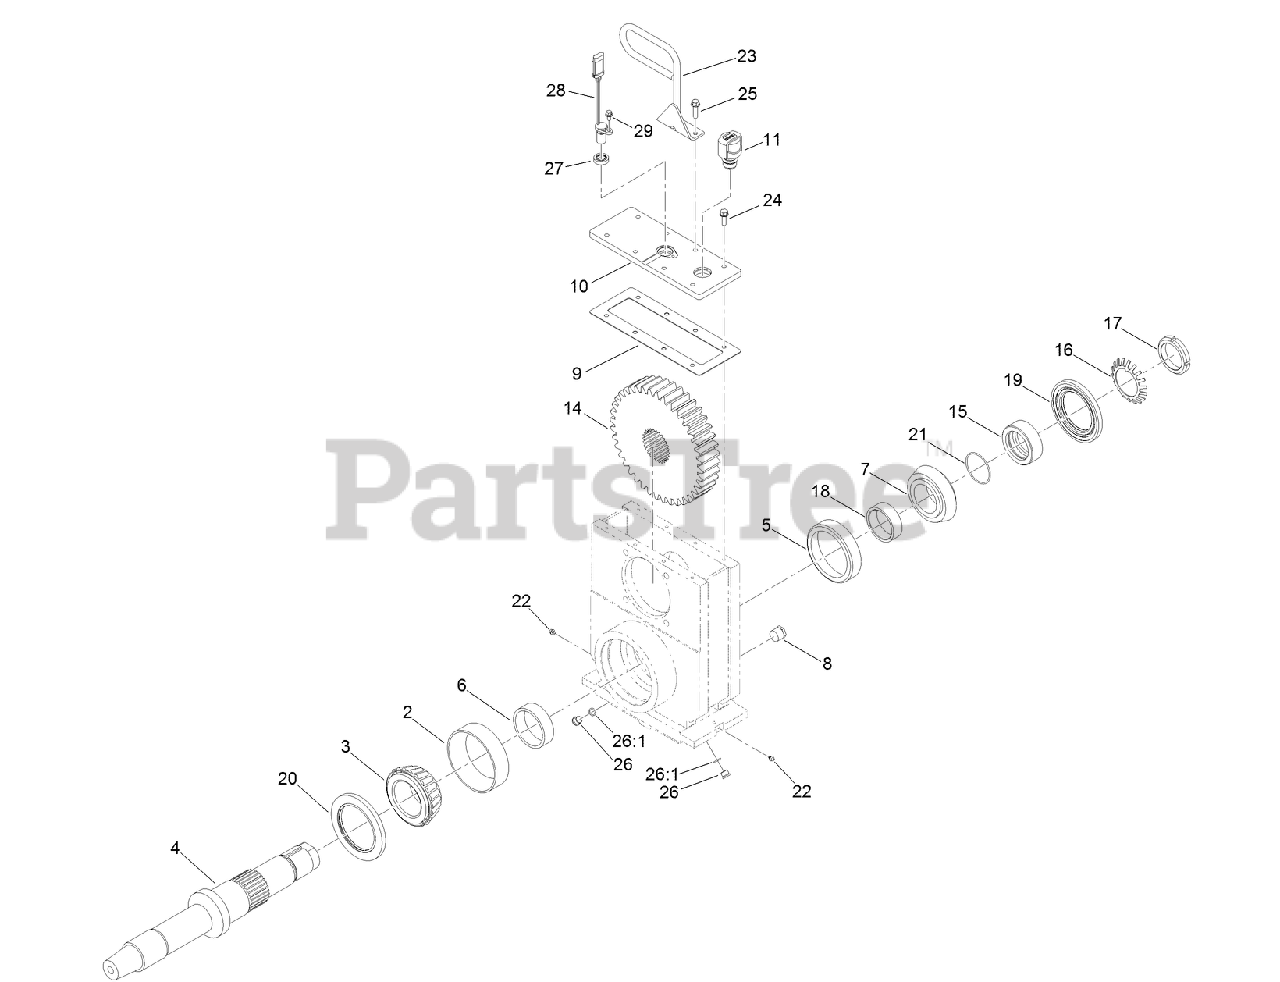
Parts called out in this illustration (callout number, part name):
2	BEARING-CUP
3	BEARING-CONE
4	SPINDLE-ROTARY
5	CUP-BEARING
6	SPACER-SHAFT
7	CONE-BEARING
8	PLUG-SITE, GLASS
9	GASKET-COVER, ROTARY BOX
10	PLATE-COVER, ROTARY BOX
11	BREATHER
14	GEAR-DRIVEN
15	SPACER-HOLDER, O-RING
16	WASHER-LOCK
17	NUT-LOCK, BEARING
18	SPACER-GEAR
19	SEAL-SHAFT
20	SEAL-ROTARY BOX
21	O-RING
22	FITTING-GREASE, ZERK
23	HOSE HOLDER
24	SCREW-HHF
25	SCREW-HHF
26	PLUG-HEX, HOLLOW
26:1	O-RING
27	SEAL-SENSOR, OIL
28	SENSOR-GEARTOOTH
29	SCREW-HHF
